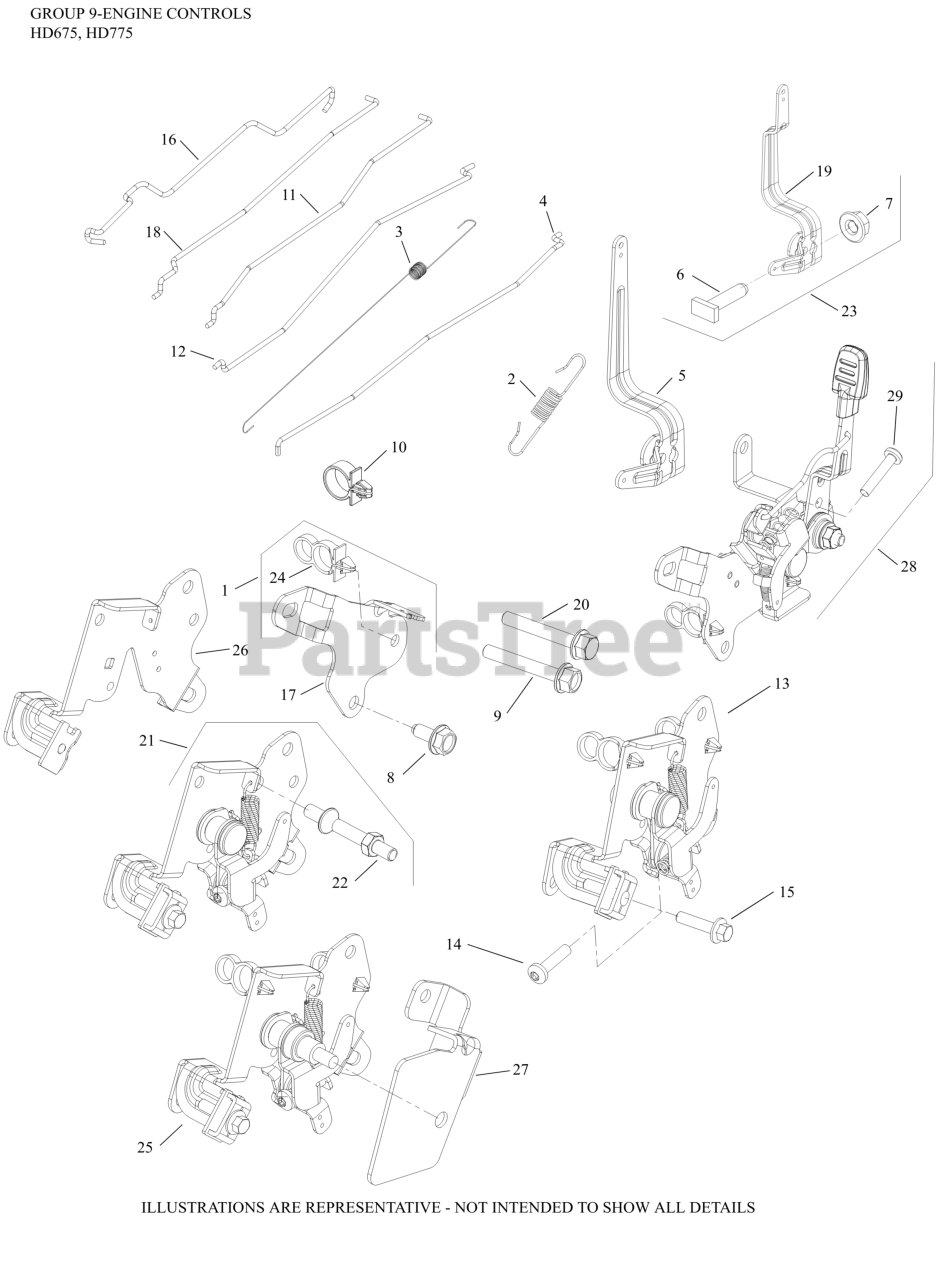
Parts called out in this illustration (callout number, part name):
2	SPRING, EXTENSION (GOVERNOR)
3	SPRING, LINKAGE
5	LEVER, GOVERNOR
6	SCREW, SINGLE HEAD (M6)
11	LINKAGE, GOVERNOR
13	CONTROL ASSY, REMOTE VARIABLE SPEED
20	SCREW, HEX FLANGE (M6)
24	CLIP, FUEL LINE
